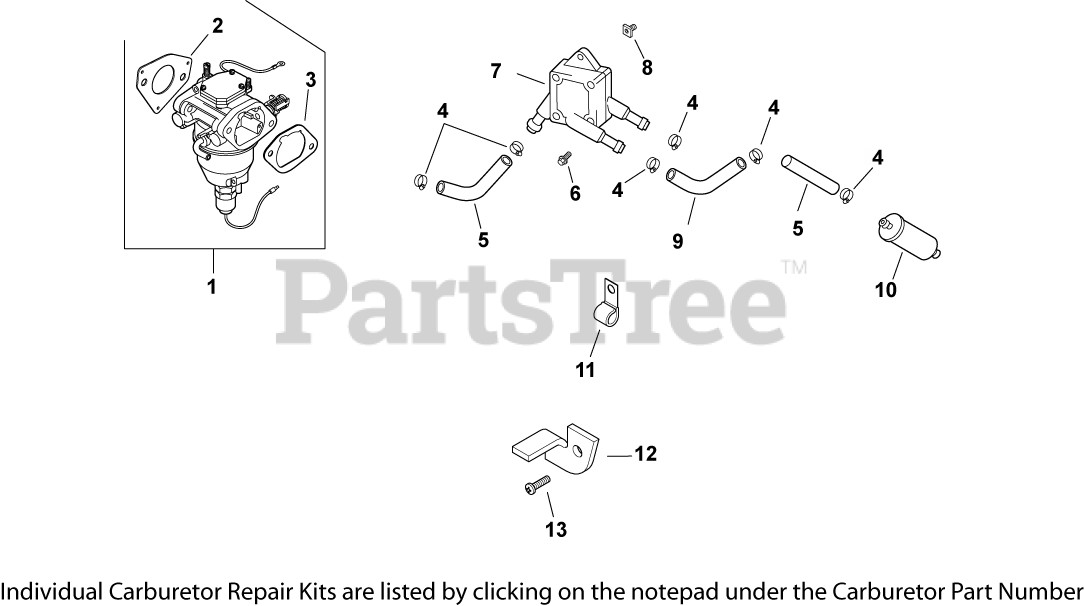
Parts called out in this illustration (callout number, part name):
1	KIT, CARBURETOR W/GASKETS
2	GASKET, CARBURETOR
3	GASKET, AIR CLEANER BASE
4	CLAMP, HOSE (KM)-USE 25 237 31-S
5	HOSE,LW PERM.FUEL 24.00"-USE 25 111 81-S
6	SCREW, TAP M6X1.7X18
7	PUMP, FUEL
8	NUT, PLASTIC - BLACK
9	LINE, FUEL 11"
10	FILTER, FUEL
11	CLIP, CABLE
12	BRACKET, THROTTLE STOP
13	SCREW, PHL THD FRM M2.5X0.45X5
